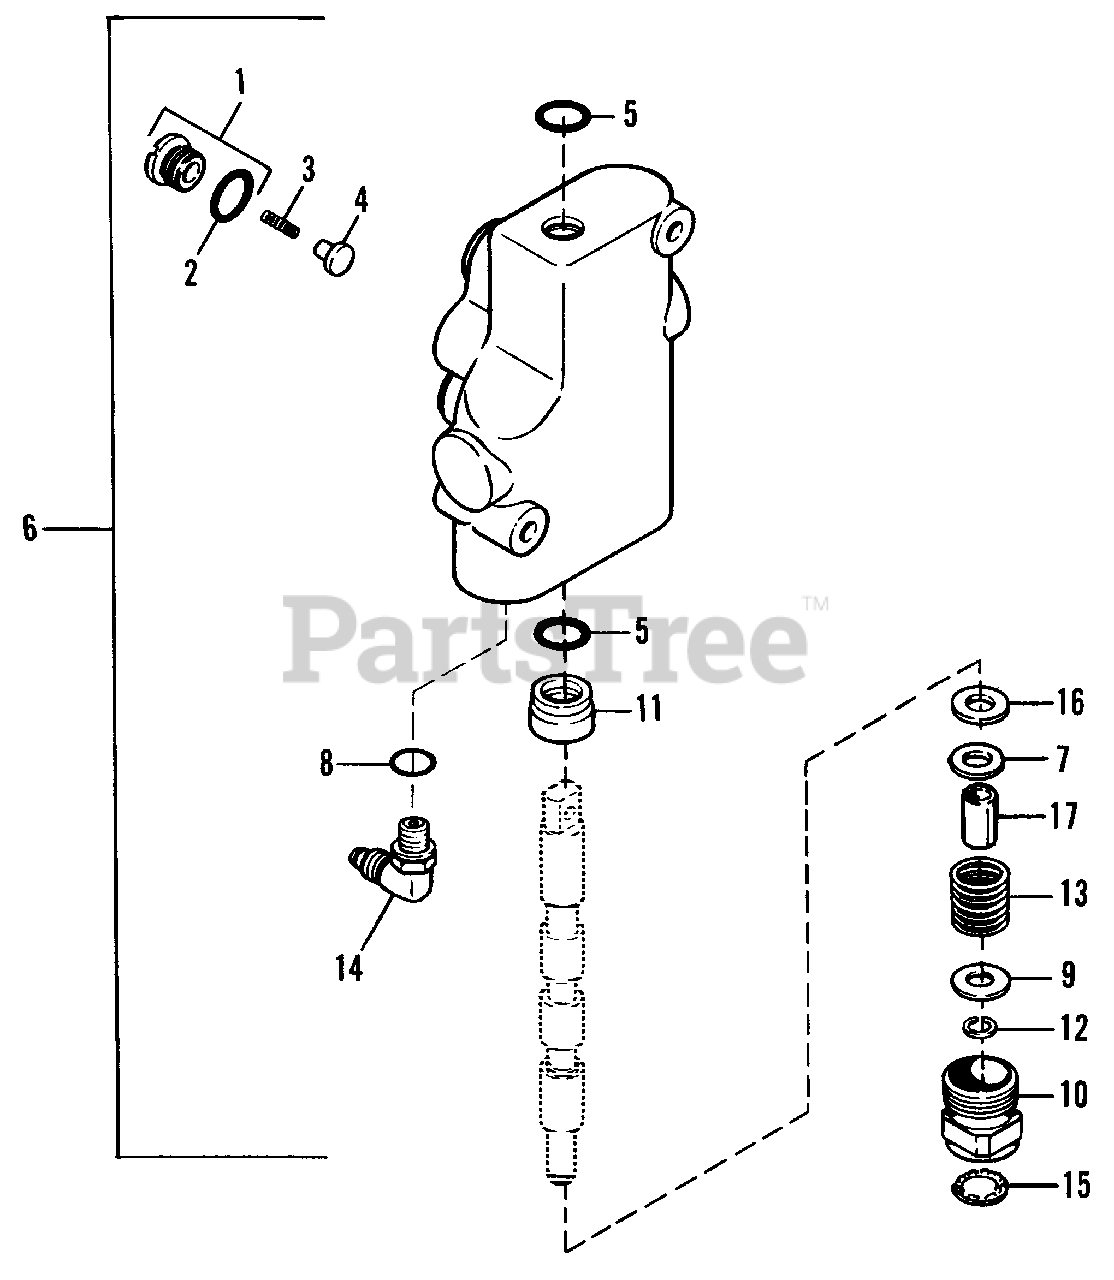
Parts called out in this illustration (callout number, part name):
1	PLUG ASSEMBLY
2	O-RING
4	PLUNGER, Lift Check
5	O-RING
6	VALVE ASSEMBLY
7	WASHER, Optional
8	O-RING
12	RING, Retaining
15	BUTTON, Insert
